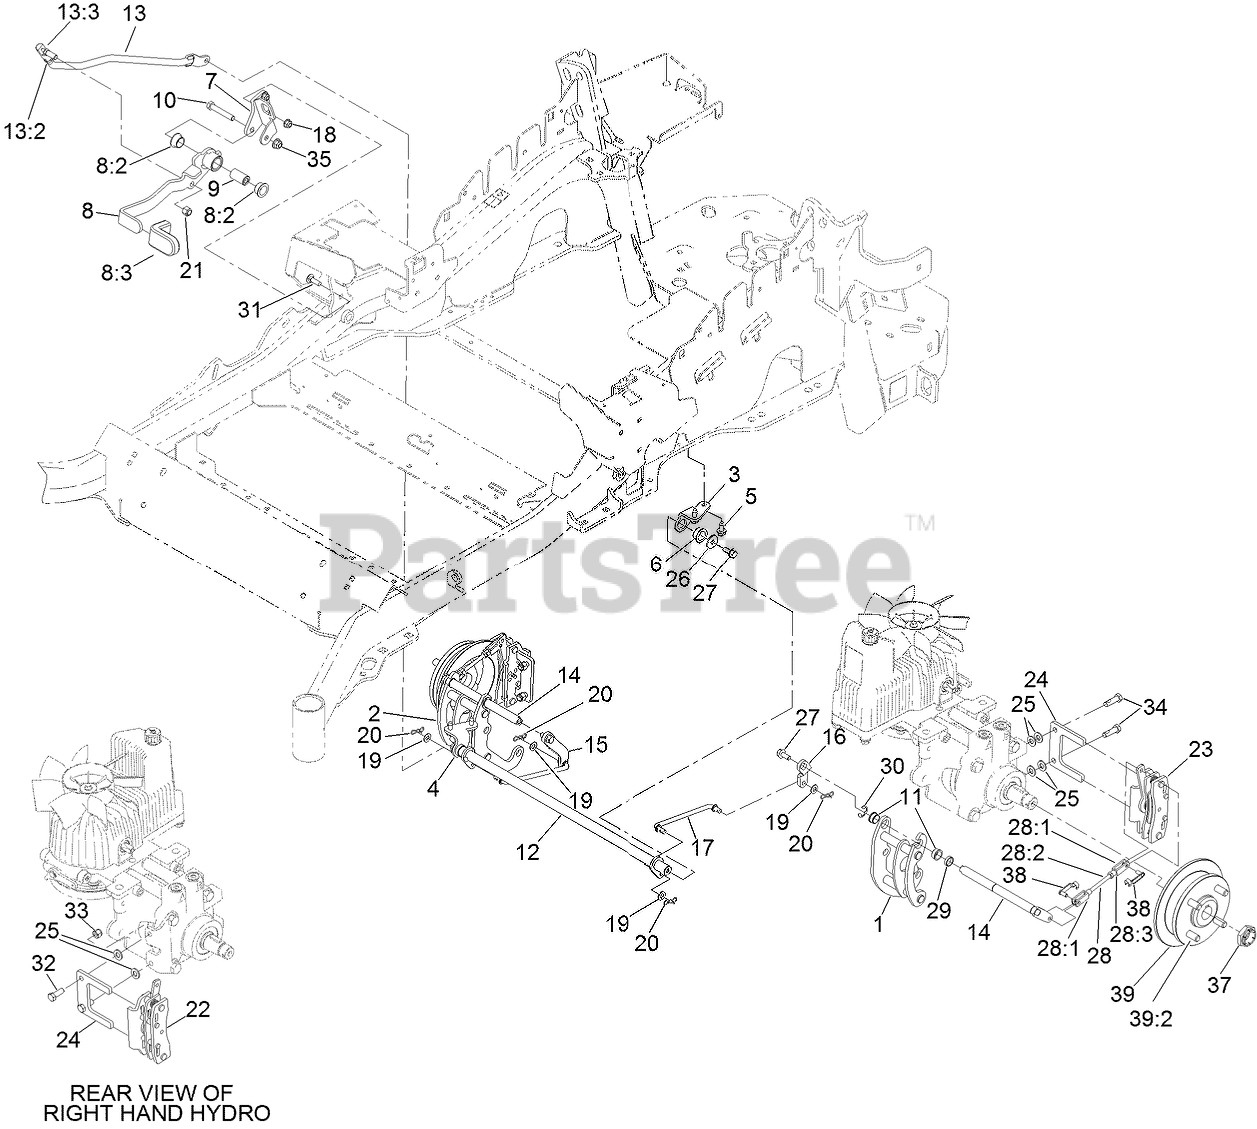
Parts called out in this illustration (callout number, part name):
1	MOUNT-BELLCRANK, LH
2	MOUNT-BELLCRANK, RH
3	MOUNT-PIVOT, LH
4	MOUNT-PIVOT, RH
5	Screw-HWH 5/16-18 X 3/4 Tf
6	BUSHING-FLANGE
7	BRACKET-MOUNT
8	Brake Lever ASM
8:2	BUSHING-FLANGE
8:3	GRIP-LEVER
9	HANDLE-PIVOT, BRAKE
10	SCREW-HH
11	BUSHING
12	Shaft-Cross
13	ASM, Front Linkage
13:2	END-TIE ROD, RH
13:3	NUT-HJ
14	BELLCRANK
15	ARM-INNER, RH
16	ARM-INNER, LH
17	Link-Mid
18	NUT-HF, NI
19	WASHER-PLAIN
20	PIN-COTTER, LOCKING
21	NUT-LOCK
22	Caliper-Brake, RH
23	Caliper-Brake, LH
24	PLATE-MOUNT, BRAKE
25	WASHER-FLAT
26	WASHER-FLAT
27	SCREW-HHF
28	REAR LINKAGE ASM
28:3	NUT-JAM
31	BOLT-CARR
32	SCREW-HH,
33	NUT-LOCK
34	Screw-HH, Patch
35	NUT-HF, NI
37	LOCKNUT
38	PIN-CLEVIS, SPRING
39	Wheel Hub ASM
39:2	STUD-WHEEL
